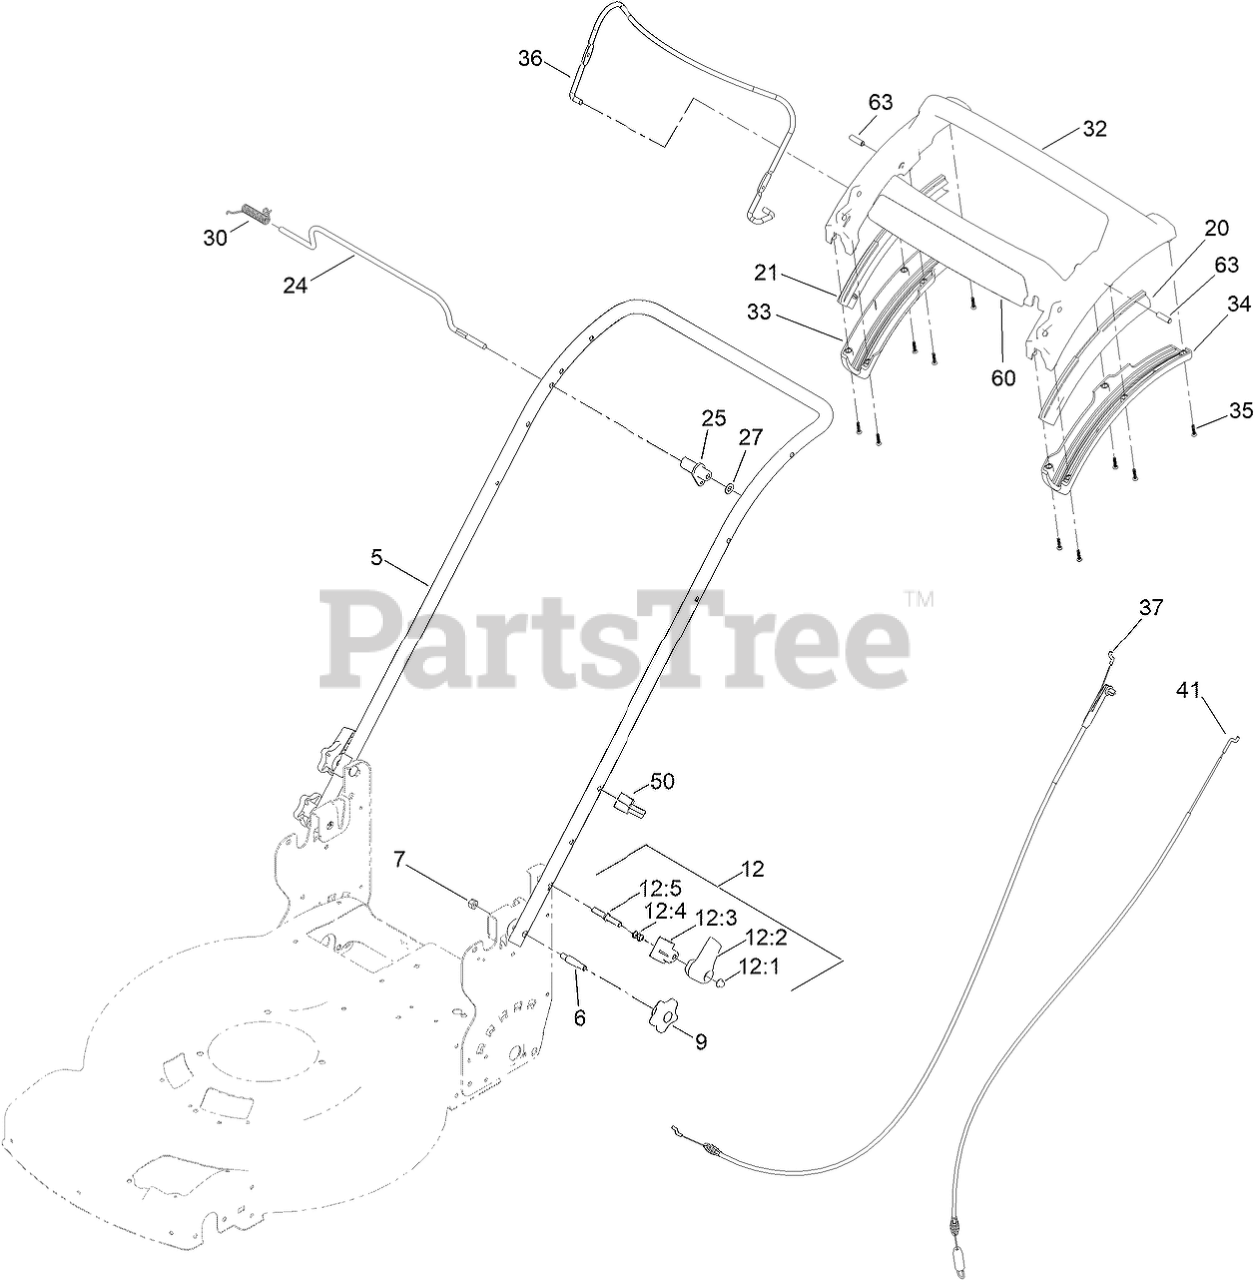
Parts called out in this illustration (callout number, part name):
5	HANDLE-CURVED
6	BOLT-SHOULDER, HANDLE
7	NUT-LOCK, NI
9	KNOB-HANDLE
12	QUICK RELEASE ASM
12:1	NUT-PUSH
12:2	LEVER-RELEASE
12:3	ANCHOR-SPRING
12:4	SPRING-COMPRESSION
12:5	ROD-RELEASE
20	GUIDE-CURVED, LH (RWD)
21	GUIDE-CURVED, RH (RWD)
24	ROD-CONTROL, TRACTION
25	LEVER-TRACTION, RWD
27	WASHER-PLAIN
30	SPRING-TORSION
32	HANDLE-PERSONAL PACE, CURVED
33	BOTTOM-HANDLE, RH
34	BOTTOM-HANDLE, LH
35	SCREW-PPH
36	BAIL-BRAKE
37	CABLE-BRAKE, PP BS
41	CABLE-TRACTION, RWD (PP)
50	GUIDE-CABLE
60	DECAL-60V, PERSONAL PACE
63	PIN-HANDLE, PP
